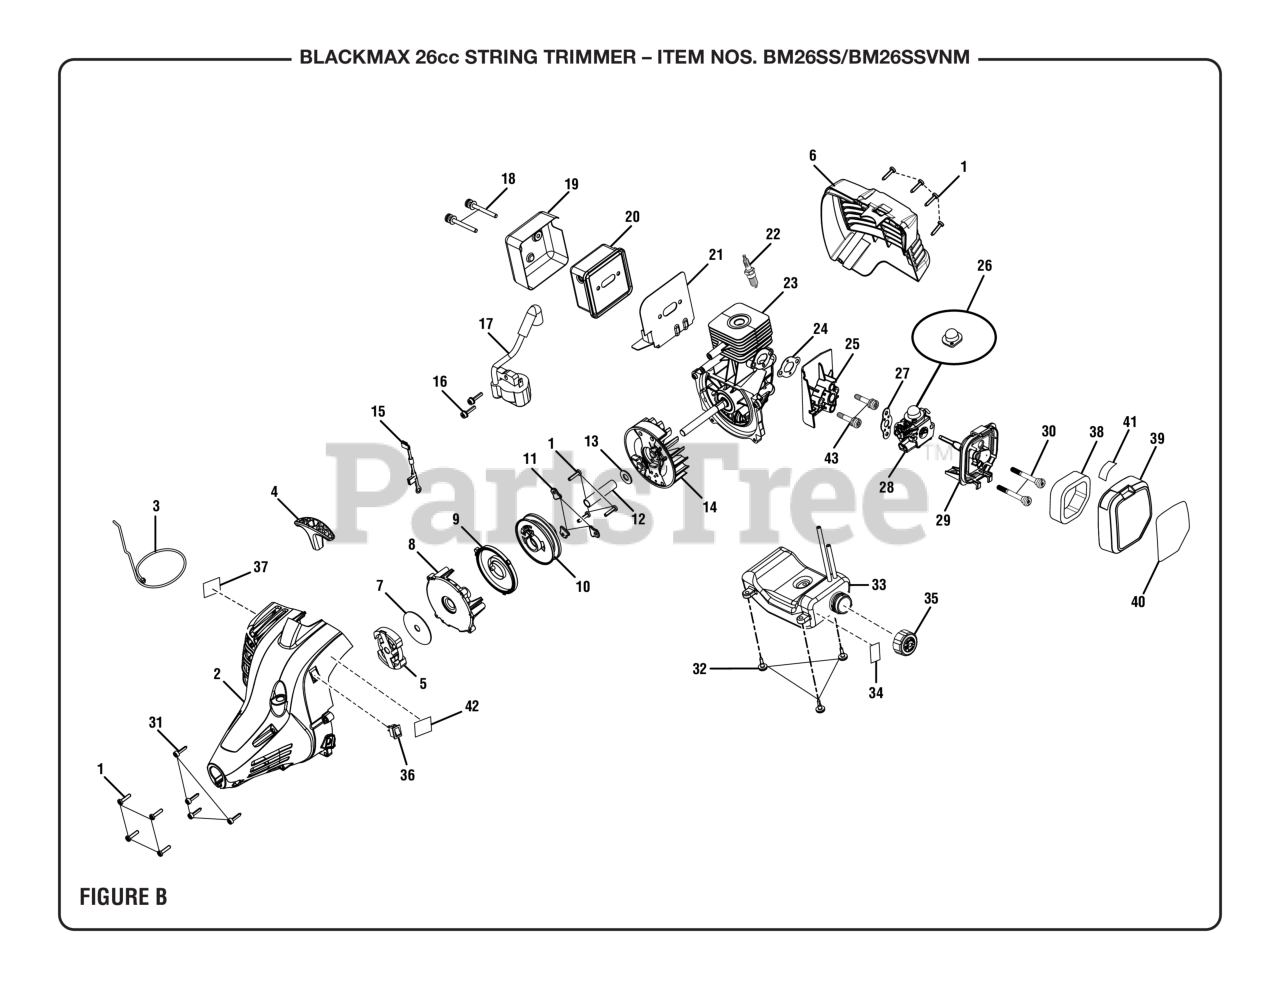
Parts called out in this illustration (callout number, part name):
1	Screw (M4 x 20 mm, T20 Torx Pan Hd. S.T.)
2	Front Housing Assembly (Inc. Key No. 37 & 42)
3	Starter Rope (42 in.)
4	Starter Grip
5	CLUTCH ASSEMBLY
6	Rear Housing
7	Washer (ID9.63 x OD50.75 x 1.10t)
8	Starter Housing
9	Spring & Container Assembly
10	Starter Pulley Assembly
11	Pulley Retainer
12	Spacer Tube
13	Washer (ID9.75 x OD20 x 1.6t)
14	Flywheel Assembly
15	Lead Assembly
16	Screw w/Washer (M4 x 19 mm, T20 Torx Pan Hd. S.T.)
17	Ignition Module
18	Screw w/Washers (10-24 x 2-1/8 in., T25 Torx Truss Hd.)
19	Muffler Housing
20	Muffler Assembly (Non "A" versions)
21	Muffler Gasket
22	SPARK PLUG CHAMPION - RCJ-6Y
23	Short Block Assembly
24	Inner Heat Dam Gasket
25	Heat Dam Deflector
28	Carburetor Assembly
29	Airbox Base Assembly
30	Screw (M5 x 45 mm, T20 Torx Truss Hd.)
31	Screw w/Washer (M4 x 16 mm, T25 Torx Truss Hd.)
32	Shoulder Screw w/Washer (M4 x 14 mm, T25 Torx Truss Hd.)
33	Fuel Tank w/Label & Cap Assembly
34	Fuel Tank Warning Label
35	Fuel Cap Assembly
36	Stop Switch (Momentary Contact)
37	Warning Label (Combustion)
38	Air Filter (Element)
39	Air Box Cover (Inc. Key No. 40-41)
40	Starting Label
41	Choke Label
42	Primer Bulb Location Label
43	Screw w/Washers (M5 x 30 mm, T25 Torx Pan Hd.)
